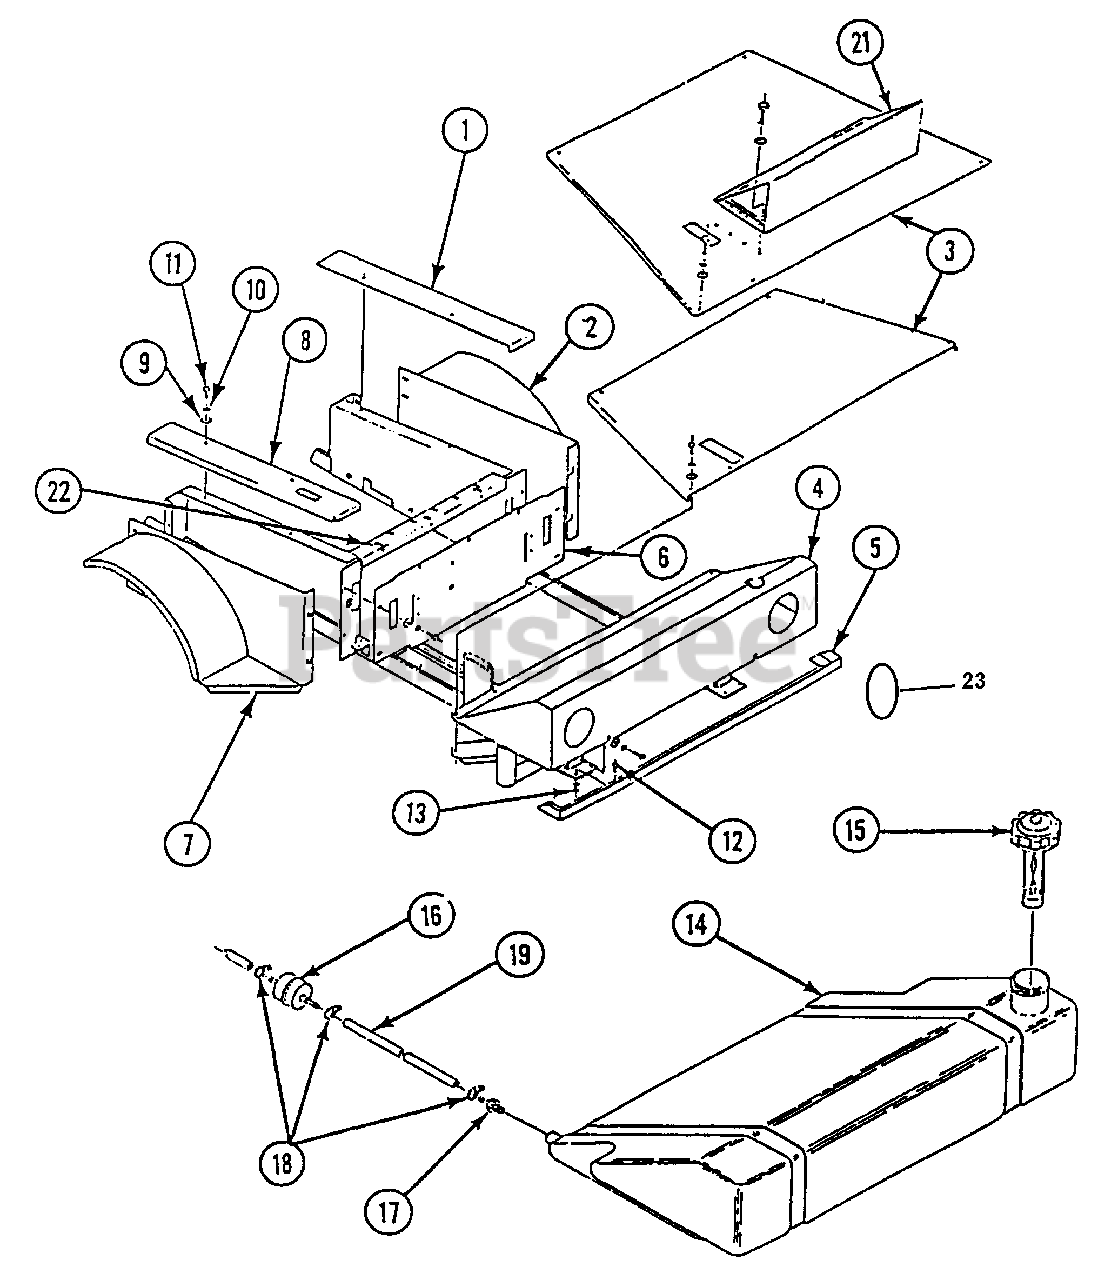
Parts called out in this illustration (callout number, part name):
1	FENDER CAP ASSEMBLY, LEFT
1	FENDER CAP ASSEMBLY, LEFT JOYSTICK
2	FENDER ASSEMBLY, LEFT
3	DRIVER FOOT MOUNTING PLATE ASSEMBLY
4	FOOT REST
6	INSTRUMENT PANEL ASSEMBLY
6	INSTRUMENT PANEL ASSEMBLY JOYSTICK
7	FENDER ASSEMBLY, RIGHT
8	FENDER CAP ASSEMBLY, RIGHT
8	FENDER CAP ASSEMBLY, RIGHT JOYSTICK
9	WASHER, 5/16 FLAT STD.
10	LOCKWASHER, 5/16 HEAVY, SPLIT SPRING
11	CAPSCREW, HEX, 5/16-18 X 3/4 GR. 5
12	CAPSCREW, HEX, 5/16-18 X 1 GR. 5
13	LOCKNUT, HEX, 5/16-18, W/NYLOC
14	GAS TANK (FRONT MOUNT MODELS)
15	GAS CAP WITH GAUGE
16	IN-LINE FUEL FILTER
17	FITTING, HOSE 1/8 NPT BRASS
18	CLAMP, 1/4 HH SCREW, 1/4 MIN.
19	FUEL LINE
21	AUXILIARY FOOT REST
22	SEAT MOUNT BRKT.
23	FENDER ASSEMBLY, LEFT
23	LIGHT MOUNT RING
